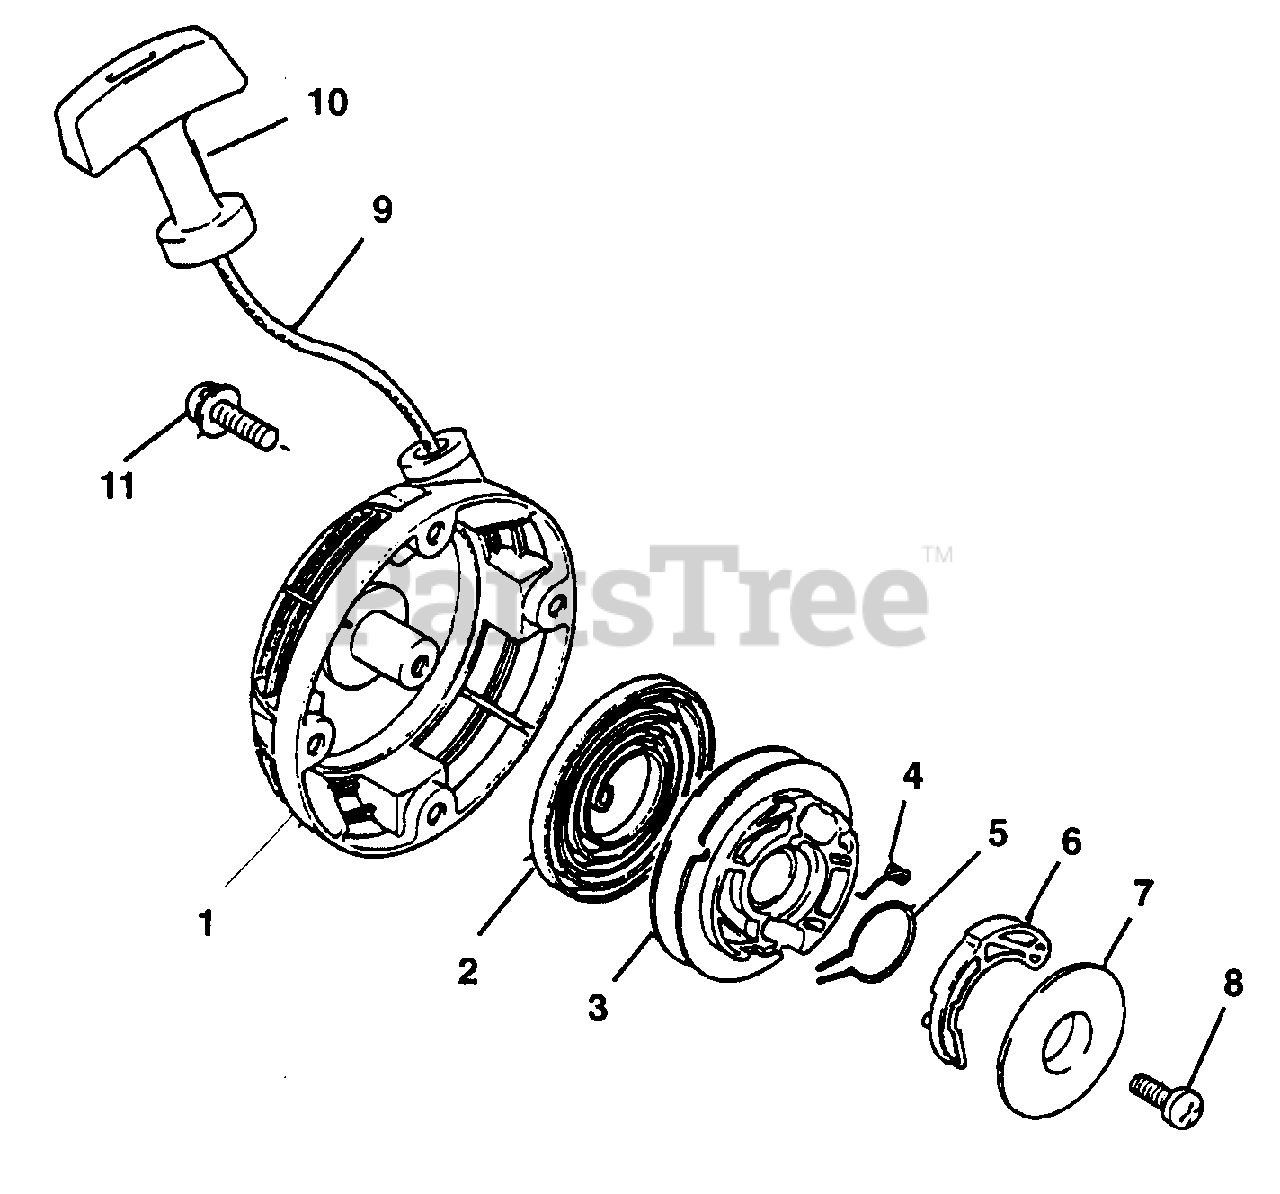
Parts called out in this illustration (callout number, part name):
1	STARTER ASSEMBLY
2	SPRING, SPIRAL
4	SPRING, RETURN
5	SPRING, FRICTION
7	PLATE, FRICTION
8	SCREW
9	ROPE, STARTER
10	GRIP
11	SCREW & WASHER
